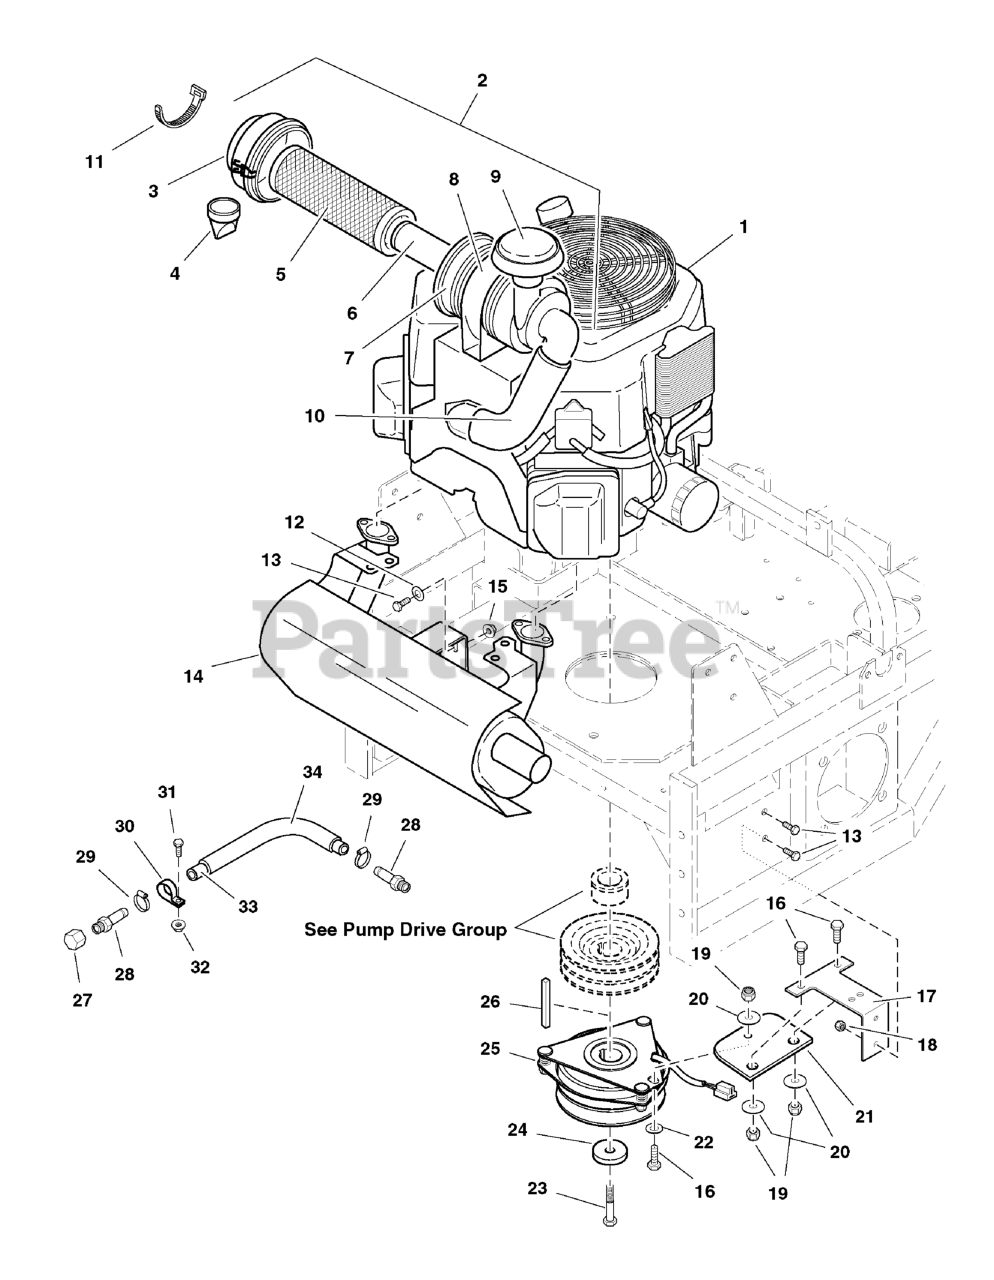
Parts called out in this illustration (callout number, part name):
1	OIL FILTER (12 050 01)
1	FUEL FILTER
5	PRIMARY PAPER ELEMENT (25 083 01-S)
6	SECONDARY ELEMENT (25 083 04-S)
9	RAIN COVER (25 324 02-S)
11	TIE WRAP, 32"
12	WASHER, 5/16" SAE
13	BOLT, 5/16-18 X 3/4 GD5
14	MUFFLER
15	NUT, 5/16-18 HEX SERRATED FLANGE (SMALL)
16	BOLT, 3/8-16 X 1" GD5 CZ
17	CLUTCH ANCHOR
18	NUT, 5/16-18 Hex Nylon Lock
19	NUT, 3/8-16 HEX NYLON LOCK
20	WASHER, 3/8" Fender
21	CLUTCH ANCHOR PAD
22	WASHER, 3/8 SAE
23	CRANKSHAFT BOLT, 7/16 x 2
24	SPACER, .45 x 1.88 x .38
25	ELECTRIC CLUTCH
26	KEY, 1/4 SQ. X 3-1/2
27	CAP, 3/8 NPT
28	FITTING, 3/8NPT-1/2" Hose, Straight
29	CLAMP, #6 Hose
30	CLAMP, Vinyl
31	BOLT, 1/4-20 x 3/4
32	NUT, 1/4-20 HEX SERR. FLANGE
33	HOSE, 13"
34	WIRE LOOM, 12"
